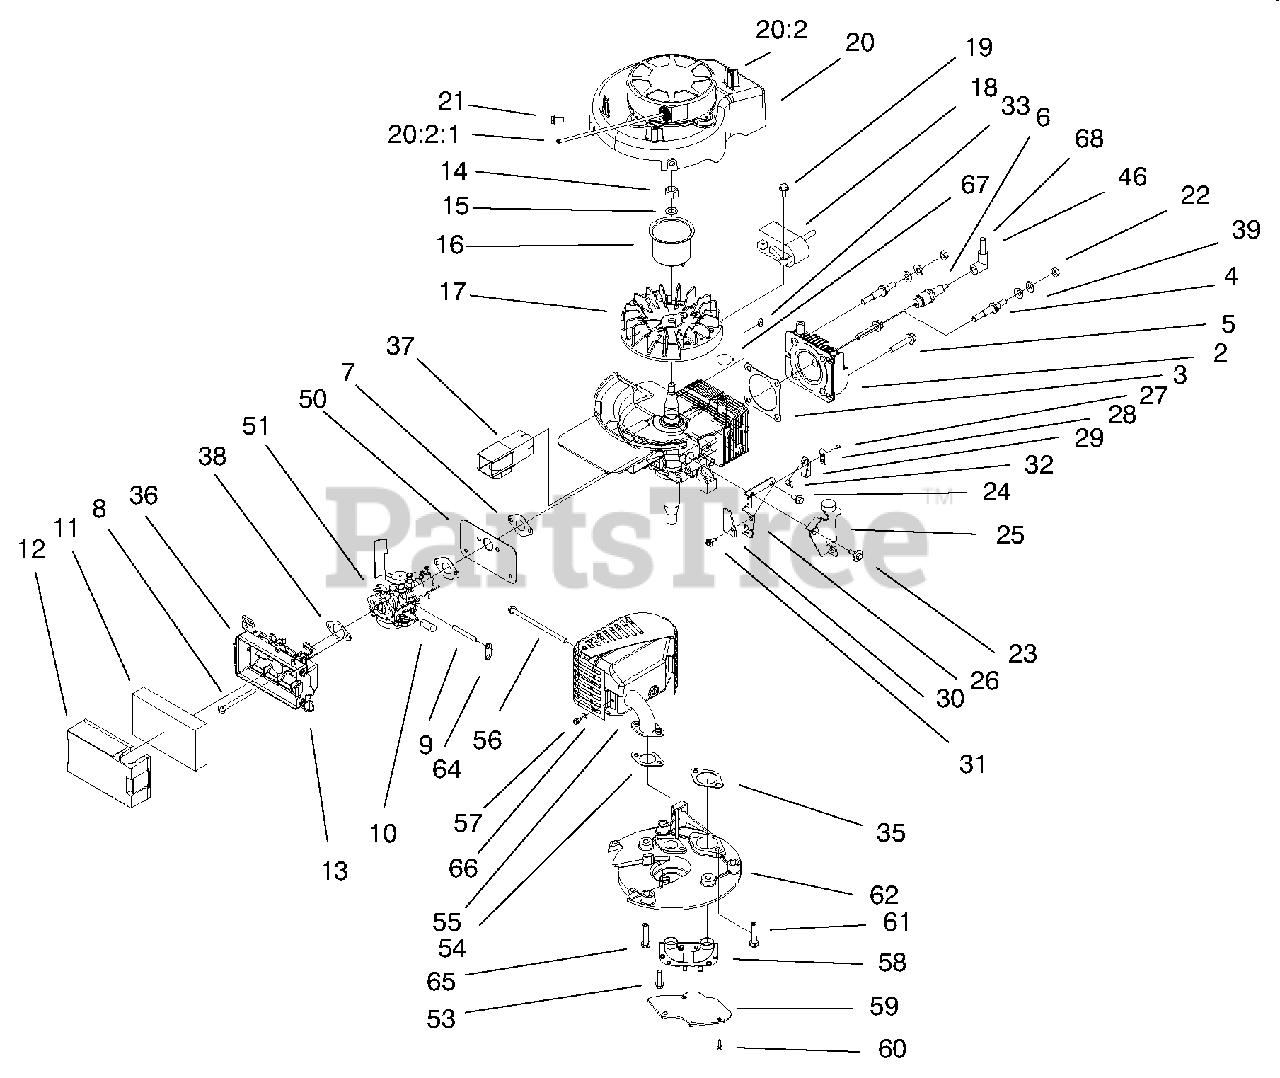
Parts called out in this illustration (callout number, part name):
3	Gasket-Head
6	Spark Plug
7	Intake Gasket
9	Primer Hose
11	Element-Air Filter
12	Cover-Air Filter
13	Retainer-Filter
15	Washer-Lock
16	Cup-Starter
17	Flywheel Machined Recoil
18	Ignition ASM
19	Screw-HWH
20	Shroud & Recoil ASM
20:2	Recoil & Decal ASM
21	Screw
22	Nut-Lock
23	Shoulder Screw Brake
24	Screw (Brake)
25	ASM-Brake Plate
26	Plate-Mount Brake
27	Rivet-Self Expand Plas
28	Strap-Insulation
29	Strap-Ground
30	Stop-Ground Strap
31	Screw-Thread Forming
32	Brake Switch Lead Wire
35	Gasket-Exhaust
36	Air Filter Base ASM
38	Gasket-Filter Base
39	Washer-Lock
46	Cover & Terminal
50	Heat Shield
51	Carburetor ASM w/Gaskets
53	Screw-HWH
55	Muffler & Guard
58	Transfer Tube
59	Cover Plate
61	Screw-HH
62	Muffler Plate Machining
64	Retainer Hose
65	Screw-HH
66	Washer-Lock
67	Tie Strap
68	High Tension Lead & Cover
